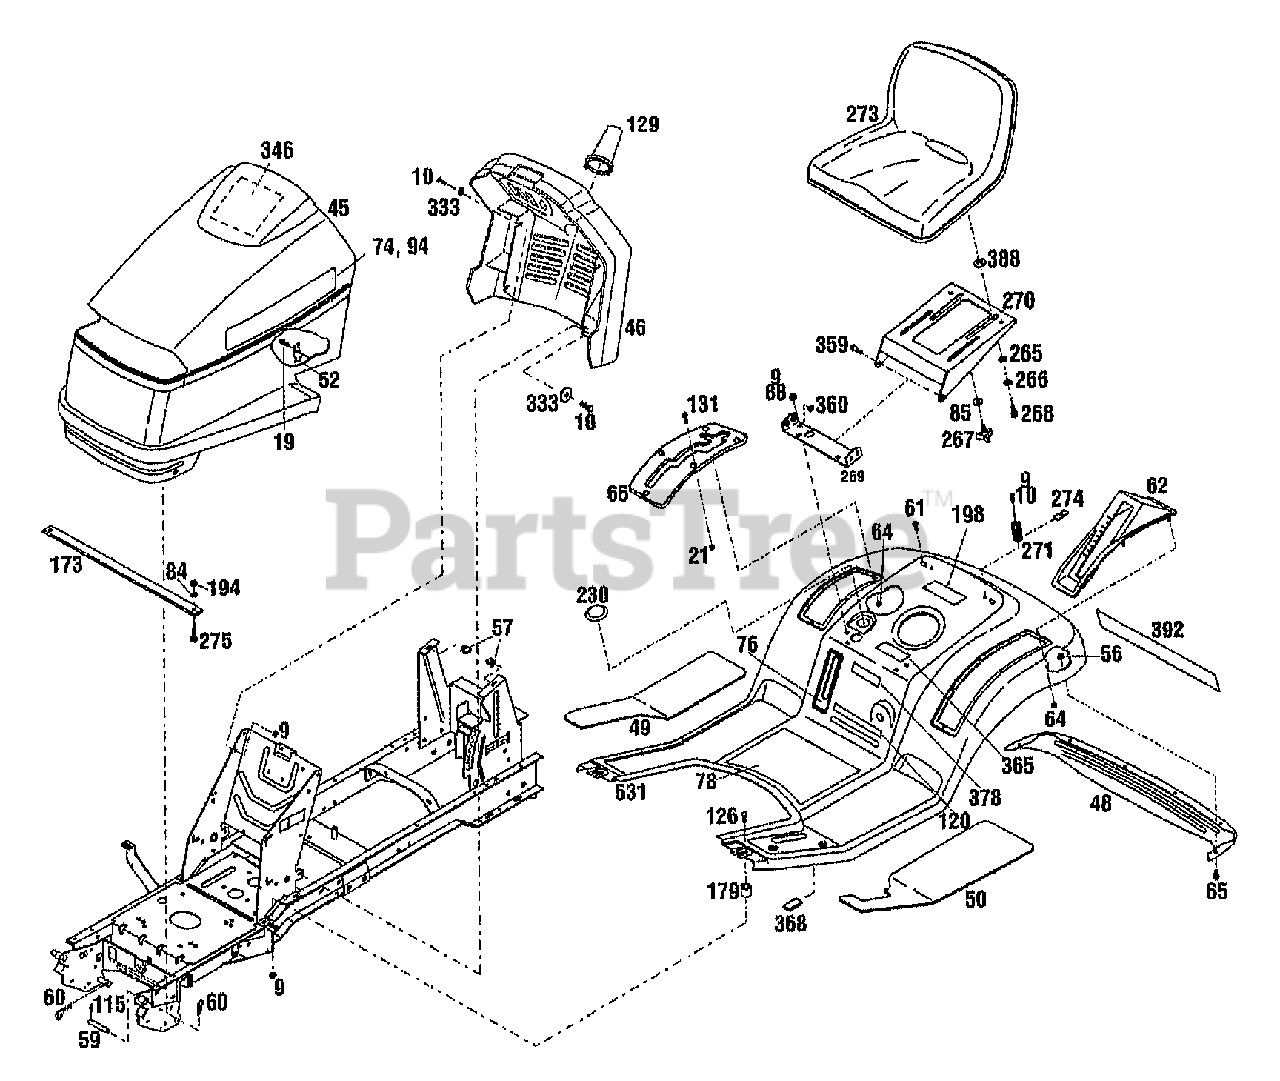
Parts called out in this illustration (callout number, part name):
9	NUT-HFLK 5/16-18 ZP
10	SCR-HHC 5/16-18X.75 GR 5 ZP
19	SCR-SPECIAL #10
21	NUT-LK 1/4-20
45	HOOD-TRACTOR
46	CONSOLE
48	TRIM-FENDER REAR
49	PAD-FOOT RH
50	PAD-FOOT LH
52	LATCH
56	NUT-HF/LK 1/4-20 ZP
57	NUT-SELF RETAIN 5/16-18
59	PIN-HOOD PIVOT
60	PIN-HITCH .125X2.56 ZP
61	SCR-LOCK
62	COVER-LIFT HANDLE
64	NUT-SELF THREADING
65	SCR-HH 1/4-20X.625
66	QUADRANT
74	DECAL-LOGO RH
74	DECAL-LOGO LH
76	DECAL-FUEL LEVEL
78	DECAL-LOGO RH
84	WASHER-LK .25 ZP
85	WASHER-FLAT 3/8 SAE
88	SCR-CARR 5/16-18X.62 G2 ZP
94	DECAL-LOGO RH
115	PIN-ROLL .188X1.0
120	DECAL-HGT INDICATOR
126	SCR-CARR 5/16-18X.75
129	COVER-STEERING
131	SCR-MACH .25-20X.62
173	STRAP-HOOD
179	SPACER-TUBULAR
194	NUT-HEX 1/4-20 ZP
198	DECAL-FUEL
230	PLUG 2.50
265	WASHER-1.06X.51X.09 NYLON
266	WASHER-BOW .74X.52X.01
268	SCR-SHLDR 3/8-16X.25 G5ZP
269	BRKT-SUPPORT SEAT
270	SUPPORT-SEAT
271	SPRING-COMPRESSION
273	SEAT-LOW BACK
274	BRKT-SPRING HOLD DOWN
275	SCR-HH 1/4-20X.625 G5 ZP
333	WASHER-1.5X.343X.104
346	DECAL-SERVICE
359	SCR-HH 3/8-16X.88 G5 ZP
360	NUT-H/LK 3/8-16
388	WASHER-FLAT
392	DECAL-MODEL
531	FENDER-REAR
